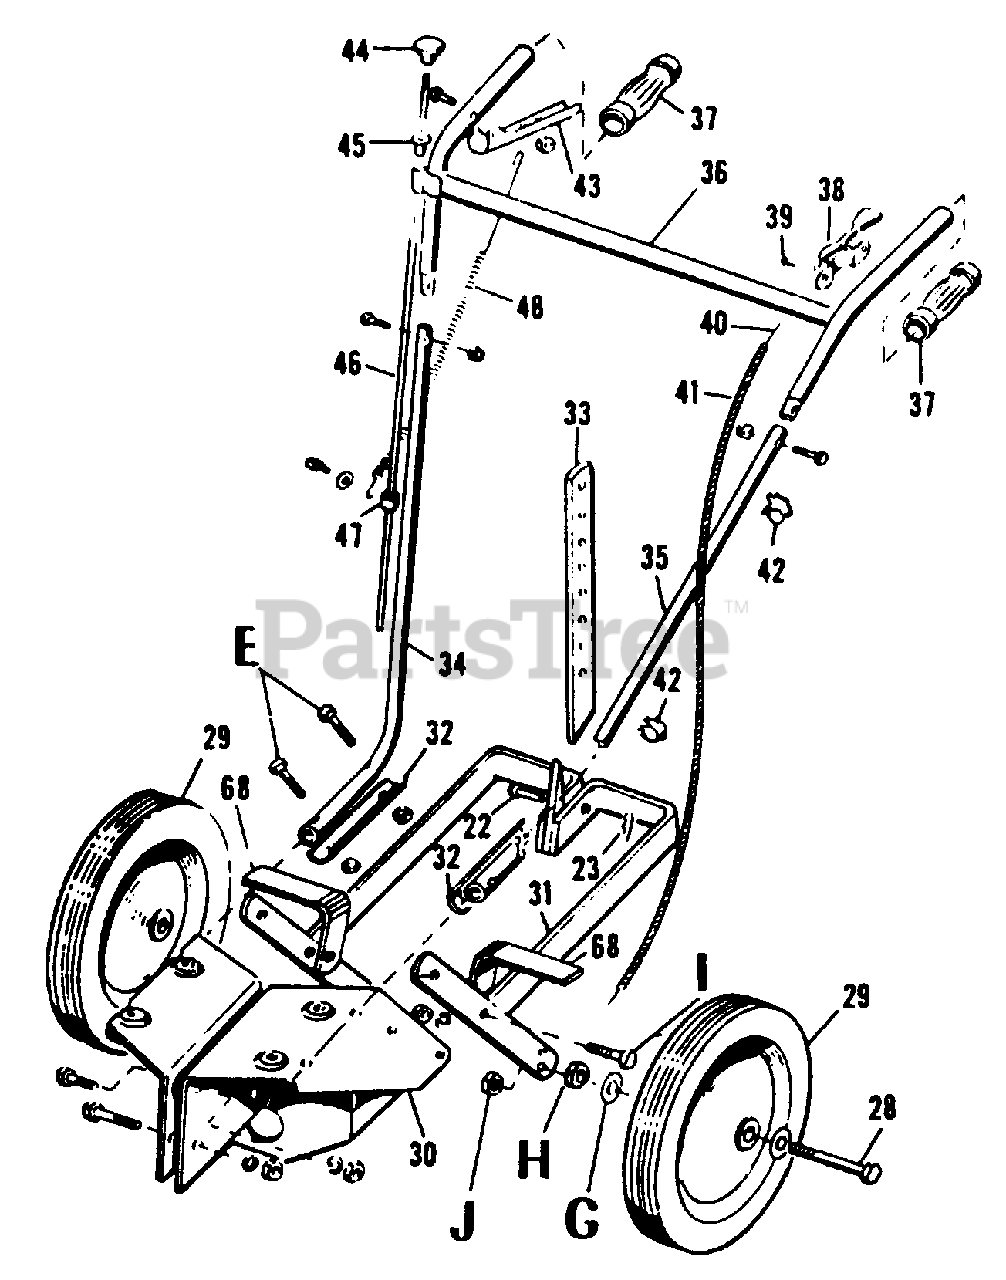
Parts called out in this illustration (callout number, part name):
28	Capscrew, Hex Head, 1/2-13 NC x 3-1/4" lg.
29	Wheel and Tire Assembly
30	Bracket Assembly, Engine
31	Frame Assembly, Rear
32	Support, Handle
33	Bar, Depth
34	Handle, R.H. Lower
35	Handle, L.H. Lower
36	Handle Assembly, Upper
37	Grip, Handle
38	Control, Throttle Lever
39	Screw, Rd. Hd., Self-Tapping #10-24 x 1/2" lg.
40	Throttle Wire
41	Throttle Cable
42	Cable Clip
43	Clutch Grip
44	Knob, Reverse
46	Rod, Reverse
48	Spring, Clutch Lever
